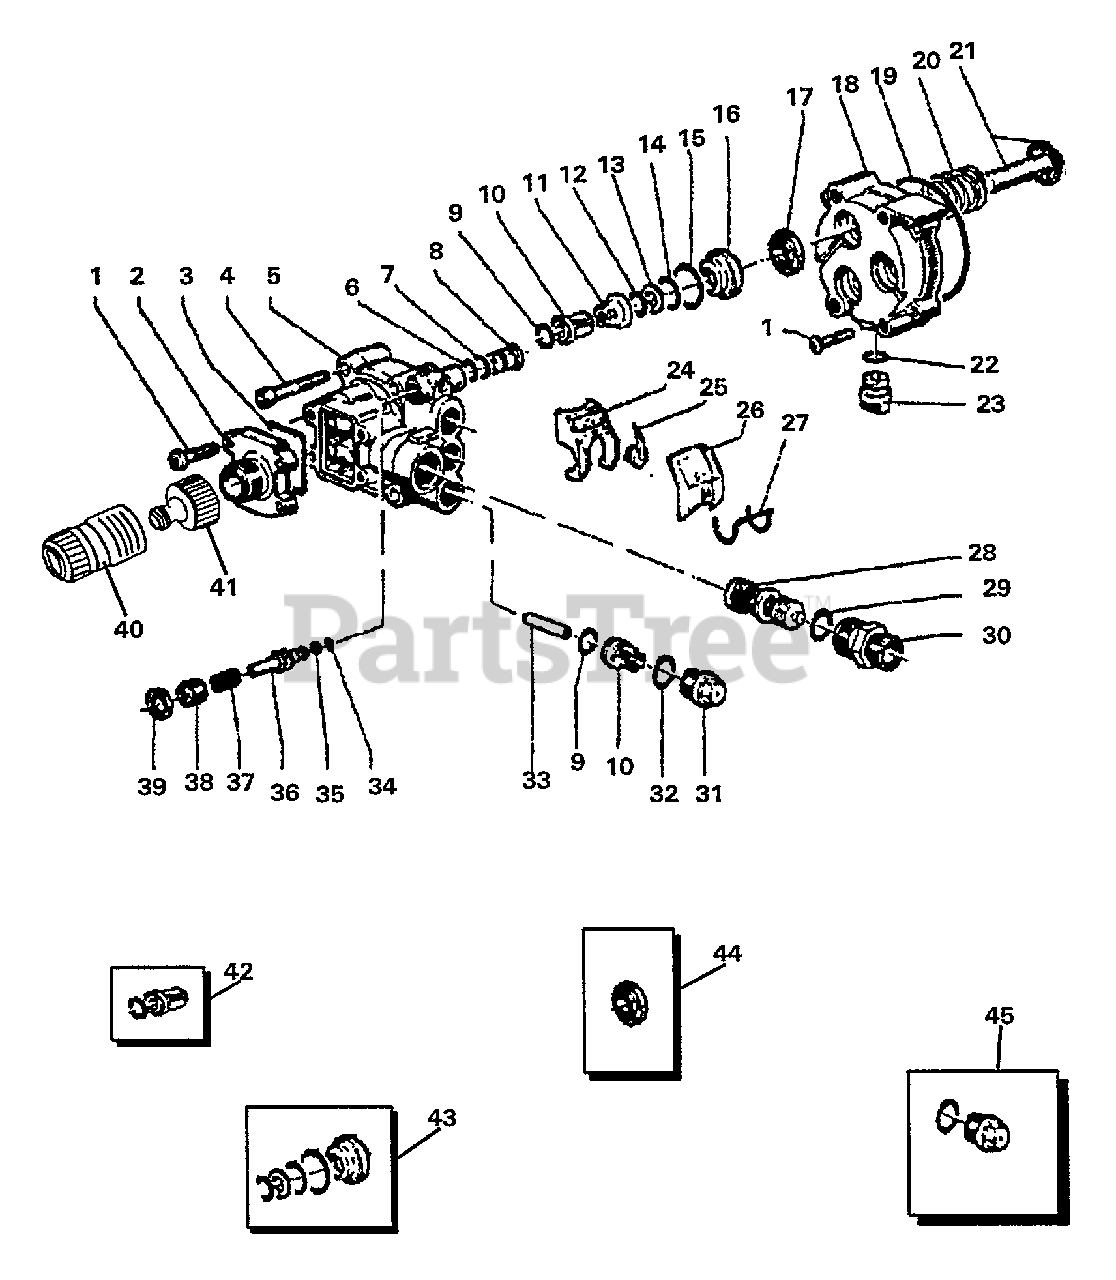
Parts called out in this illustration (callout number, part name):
1	SCREW - 6X30
3	O-RING - 1.549 X .103
4	SCREW - 8X50
5	HEAD, PUMP
6	O-RING
7	O-RING - .296 X .084
8	CYLINDER, PRESSURE GAUGE
9	O-RING, .489 X.070
10	UNIT VALVE
11	SPACER
12	O-RING - .469 X.103
13	RING
14	O-RING - .739 X .070
15	O-RING - .937 X .103
16	SPACER
17	SEAL, OIL
18	FLANGE
19	O-RING - 3.237 X .103
20	SPRING
21	PISTON
22	O-RING
23	PLUG
24	DIAL
25	INDICATOR
26	COVER, DIAL
27	SPRING
28	VALVE KIT
29	O-RING - .797 X.103
30	FITTING, OUTLET
31	PLUG, M18
32	O-RING - .614 X .070
33	PIN
34	O-RING - .118 X .079
35	RING, BACK-UP - .114 X .070
36	GAUGE, PISTON
37	SPRING
38	SCREW - 14X1
39	NUT - 14
40	COUPLING, QUICK CONNECT - FEMALE
41	COUPLING, QUICK CONNECT - MALE
42	VALVE KIT
43	VALVE PACKING KIT
44	OIL SEAL KIT
45	PLUG KIT
